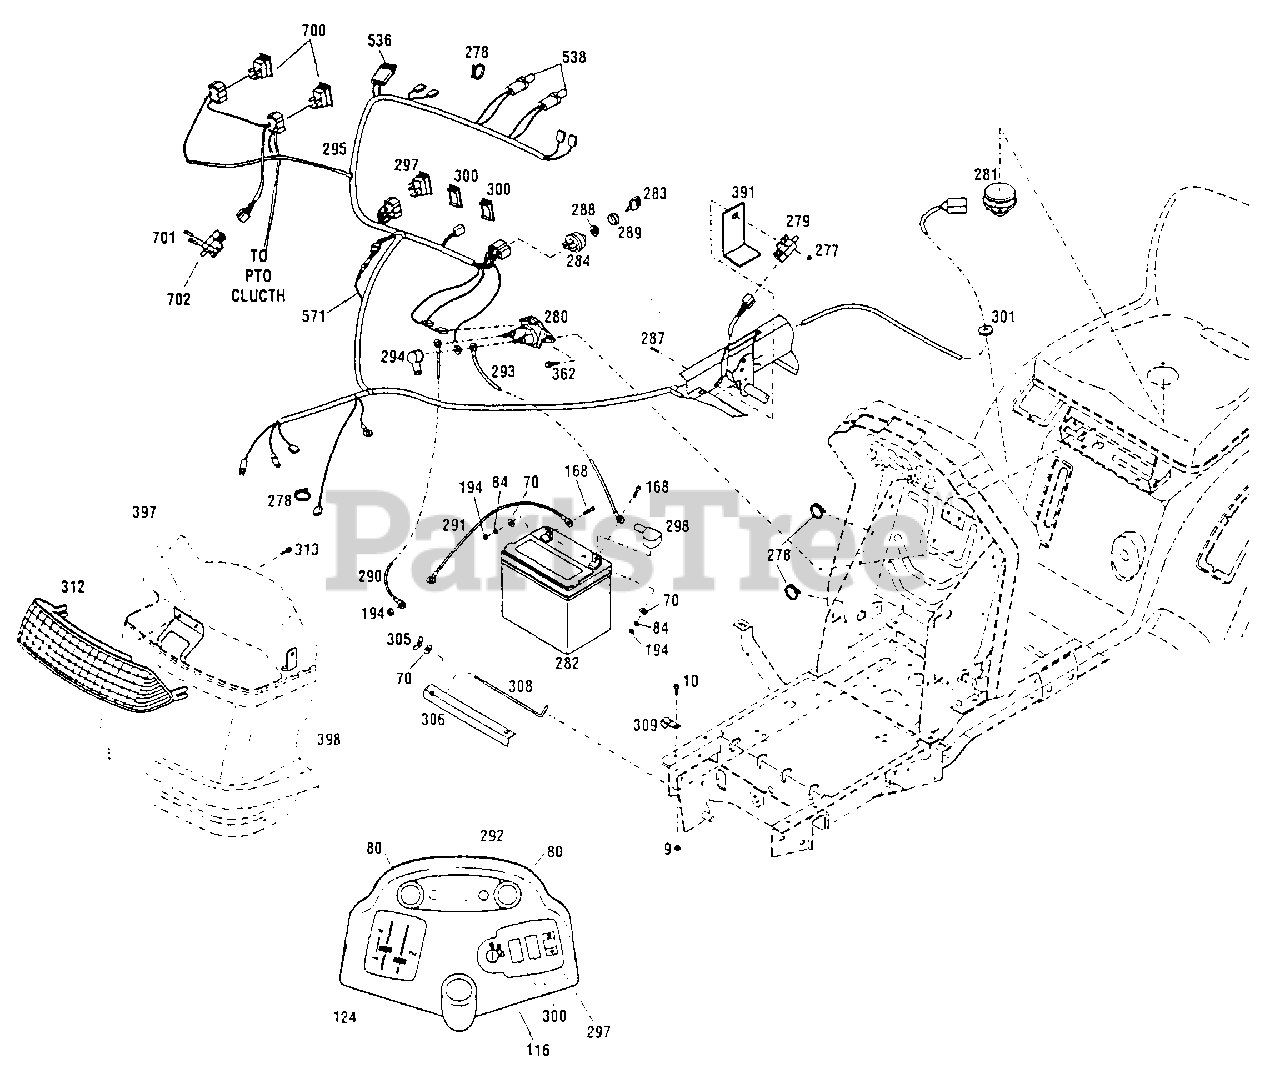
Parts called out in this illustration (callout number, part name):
9	Flange Nut, 5/16-18
10	Hex Head Screw, 5/16-18 x 3/4
70	Flat Washer, 1/4
84	Lock Washer, 1/4 SAE
116	Ignition Decal
124	Control Decal
168	Screw, 1/4-20 x 3/4
194	Nut, 1/4-20
277	Keps Nut, #10-24
278	Cable Tie
279	Clutch/Brake Interlock Switch
280	Solenoid
281	Seat Switch
282	Battery (Service only)
284	Ignition Switch
287	Sems Screw, #10-24 x 5/8
288	Ignition Switch Mounting Nut
289	Cap
290	Starter Cable
291	Negative Battery Cable
292	Warning Lens
293	Positive Battery Cable
294	Solenoid Boot
295	Main Harness
297	PTO Switch
298	Terminal Boot
300	Switch Cover
301	Grommet
305	Wing Locknut, 1/4-20
306	Battery Clamp
308	Hook Bolt
309	J-Clamp
313	Self-Threading Screw
362	Screw, 1/4-20 x 1/2
391	Switch Bracket
397	Lens Retainer
398	Retaining Clip
536	Fuse, 20 Amp
538	Panel Light Bulb
700	Relay
701	Screw
702	Safety switch
